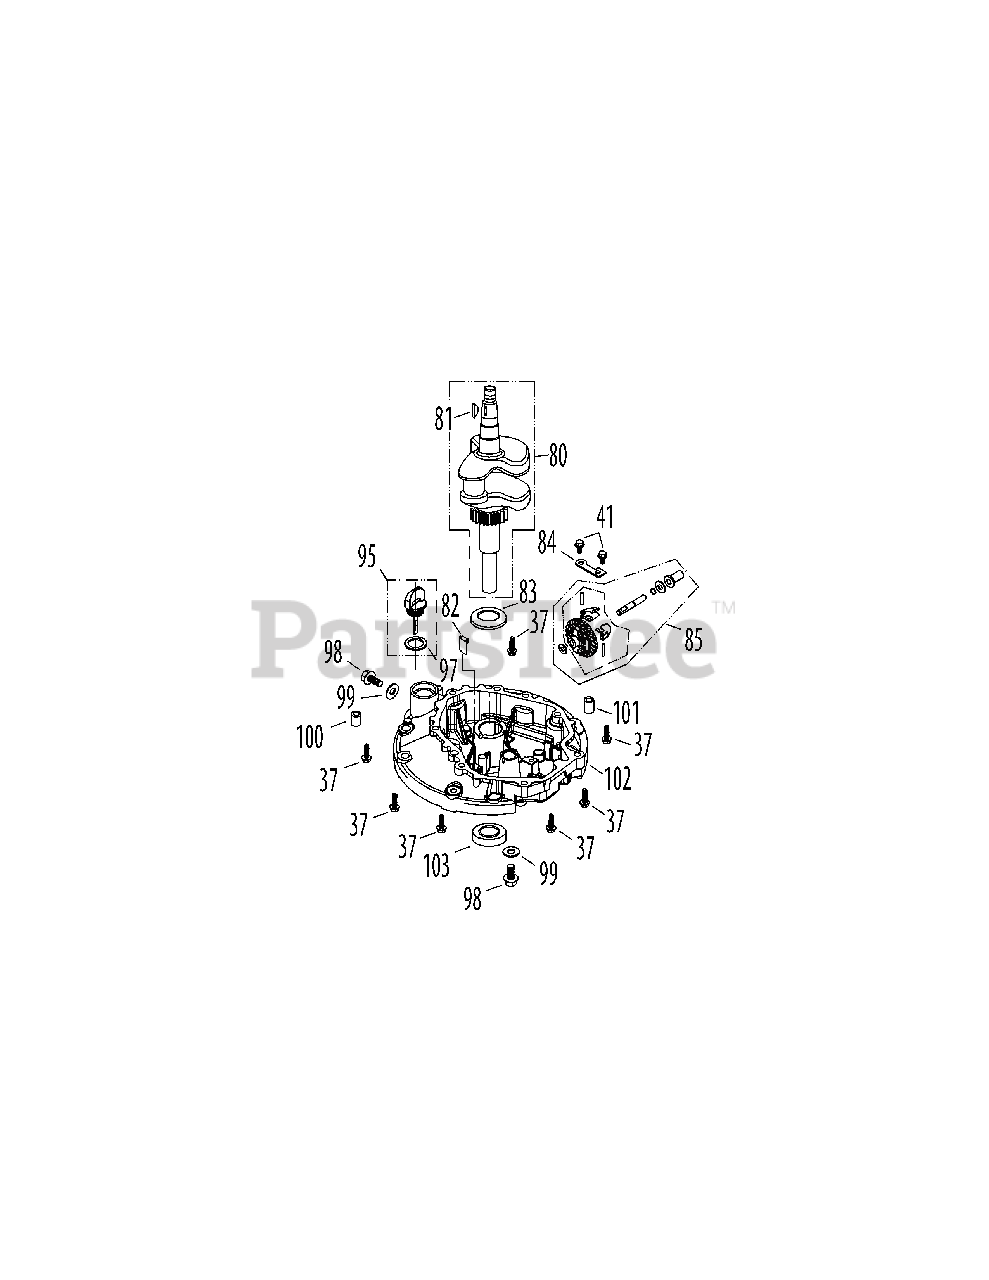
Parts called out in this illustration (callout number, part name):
37	Bolt M6x28
38	Ignition Coil Assembly
41	Bolt M6×14
80	Crankshaft Assembly
81	Woodruff Key
82	Oil Return Seal
83	Crankshaft Thrust Washer
84	Governor Gear Mounting Plate
85	Governor Gear/Shaft Assembly
95	Dipstick Assembly
97	Dipstick O-Ring
98	Oil Drain Plug
99	Oil Drain Plug Washer
100	Crankcase Cover Dowel 9x14
101	Crankcase Cover Dowel 7x14
102	Crankcase Cover
103	Lower Crankshaft Seal
